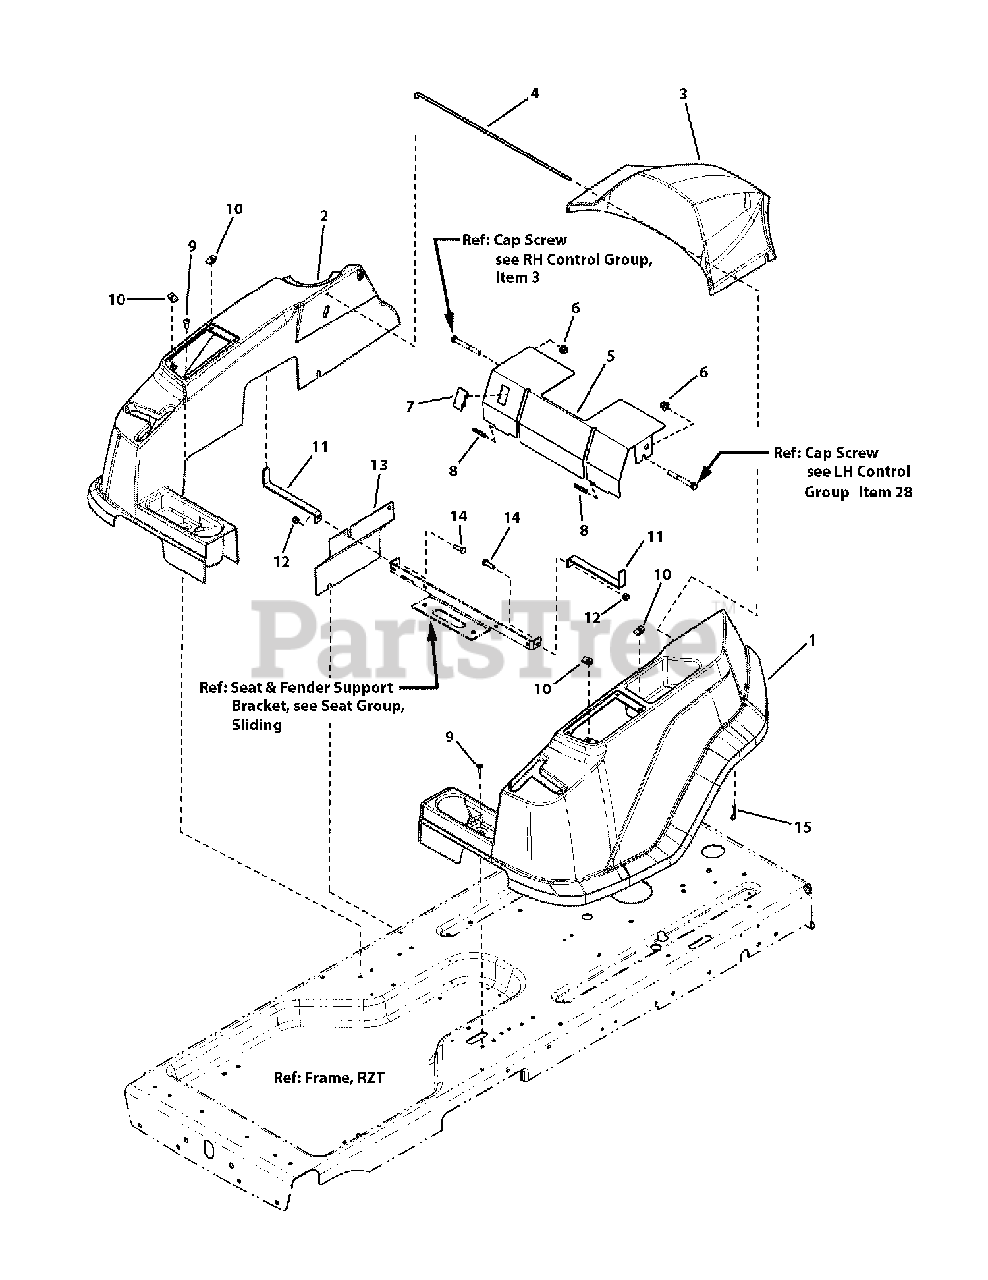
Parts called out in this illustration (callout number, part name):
1	FENDER, LH
2	FENDER, RH
3	COVER, Engine
4	ROD, Pivot, Hood
5	COVER, Battery
6	NUT, 3/8-16 Hex Flange Esna, Black
7	PLUG, Switch Hole
8	STRIP, Trim, 1-1/2" long
9	SCREW, 1/4-20 x 3/4" Pan Head Self-Tap (Torx) BZ
10	U-NUT, 1/4-20
11	BRACKET, Support, Fender
12	NUT, 5/16-18 Hex Nyloc, YZ
13	PLATE, Side, RH
14	SCREW, 5/16-18 x 1" Hex Head Cap, GR 5, YZ
15	HAIRPIN, Quick, .080 Wire
